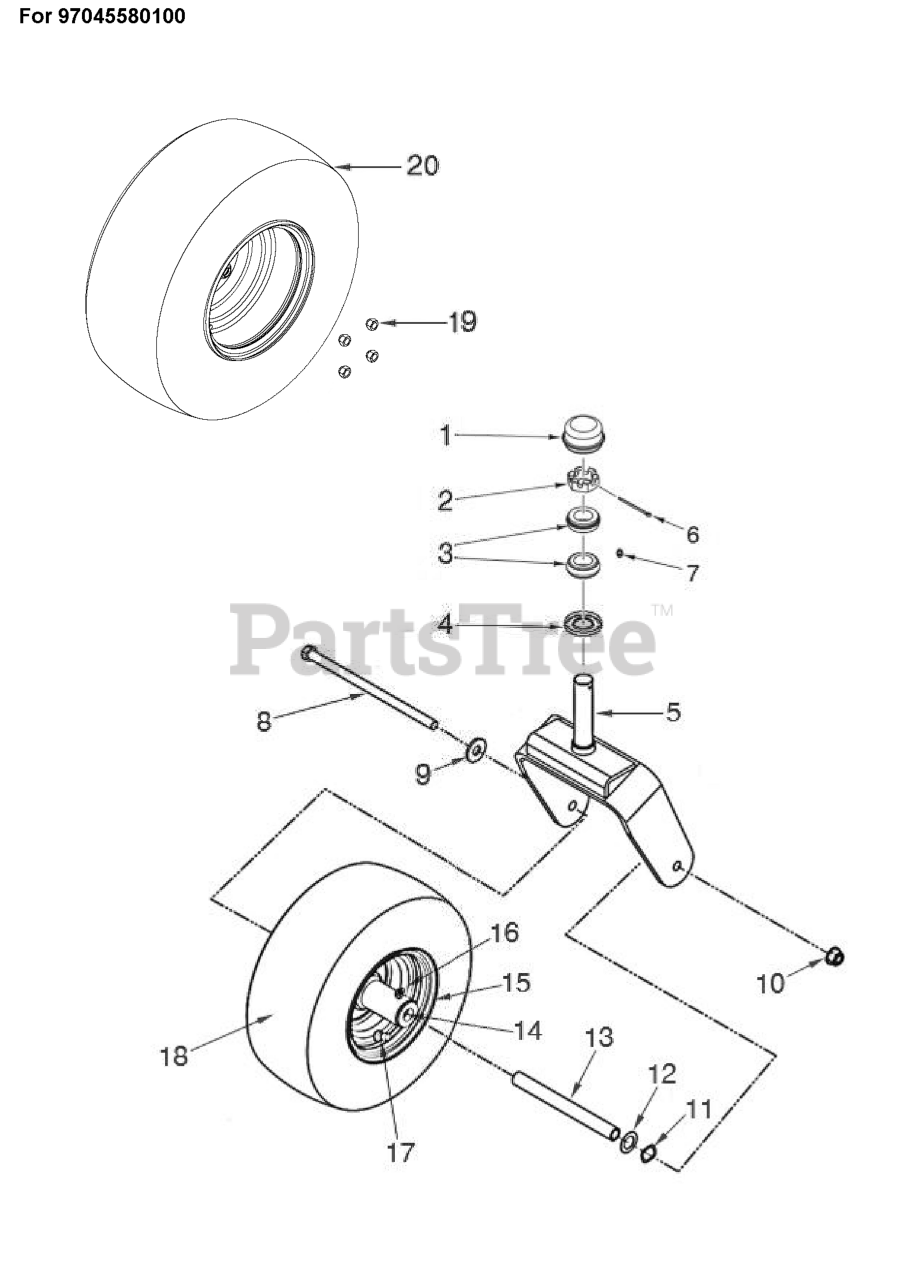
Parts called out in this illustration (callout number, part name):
3	TAPERED ROLLER BRG
5	FORK.CASTER.ASM.PNT.668
8	GSPW Screws
10	NUT 1/2-13 HEX FLANGE NYLOK CL
11	WASHER, .825 X 1.087, WAVE
13	SPACER, PIVOT
14	ROLLER BEARING-CAGED 3 1/4'
14	BEARING RETAINER
15	TIRE.ASSEM.CASTER.13X6.5-6.SIL
16	ZERK
17	VALVE STEM TR-412
18	TIRE - SMOOTH 13X6.50-6
19	NUT.1/2-20.UNF-2B.GR.8.YL
20	WHEEL.ASSEM.22X10-10.SILVE.ZTR
